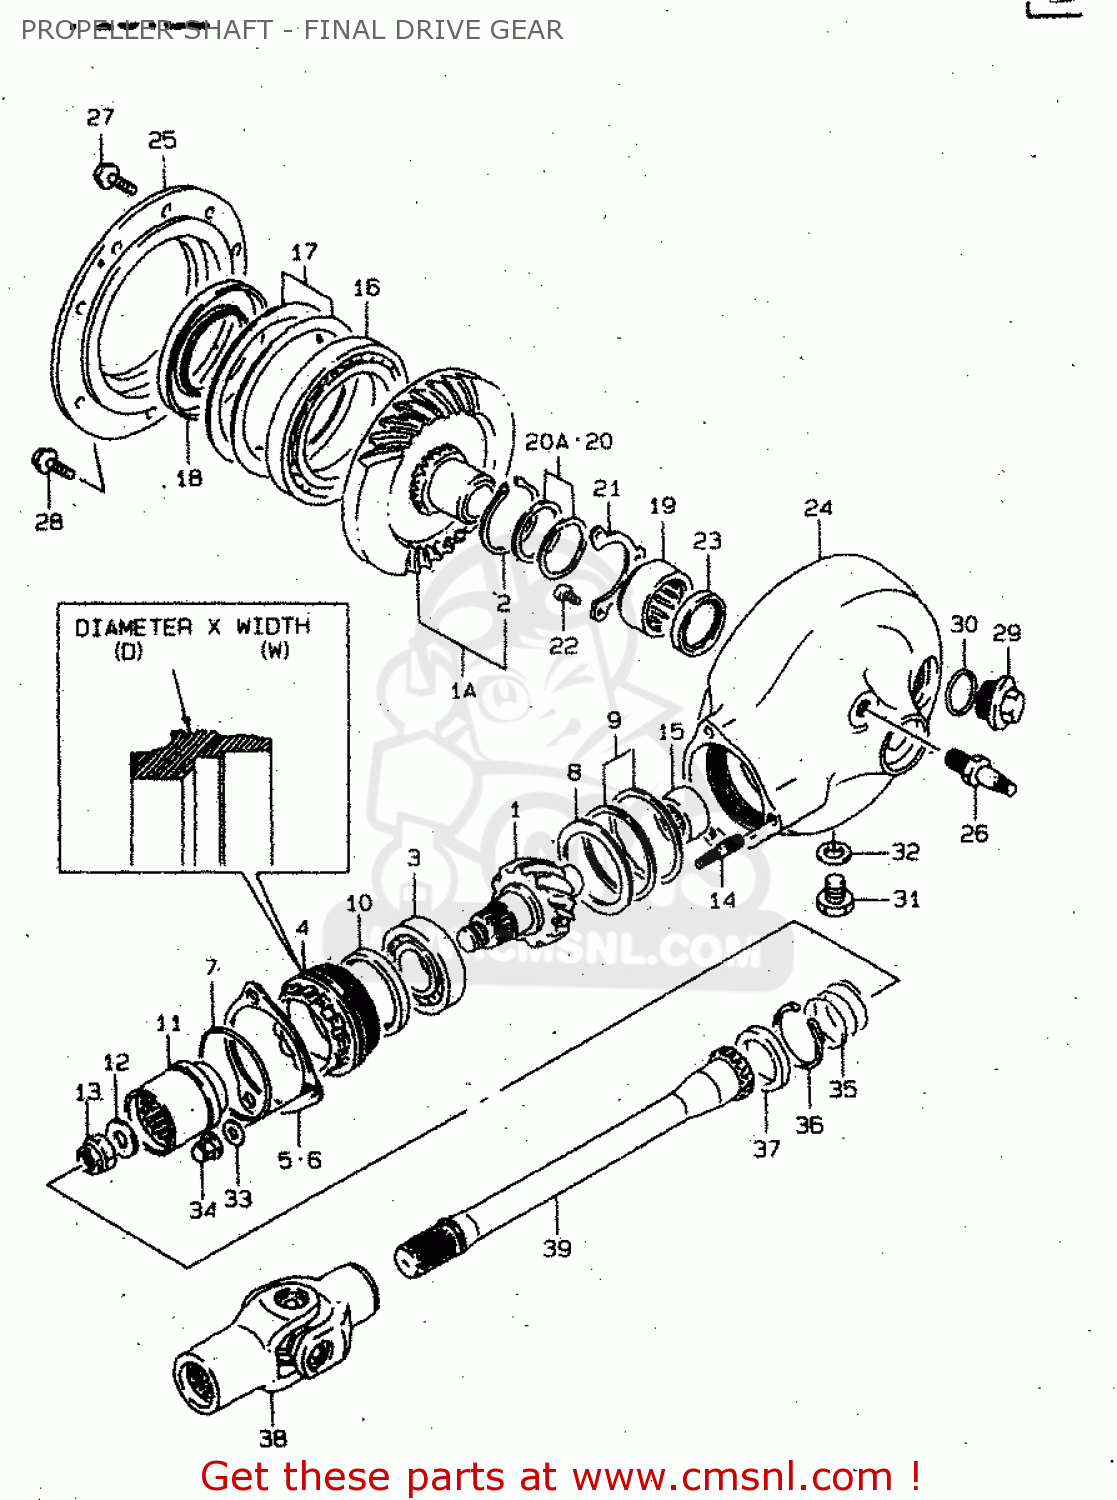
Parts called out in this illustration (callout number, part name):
1	GEAR,FINAL DRIVE BEVEL
1A	GEAR,FINAL DRIVEN BEVEL
2	.CIRCLIP
3	BEARING(28X68X18)
4	STOPPER,FINAL DRIVE BEARING
5	PLATE,BEARING STOPPER
6	PLATE,BEARING STOPPER
7	O RING(D:3.1,ID:63.9)
8	WASHER(54X68X1.5)
9	SHIM SET,FINAL DRIVE GEAR
10	SEAL,OIL
11	COUPLING,FINAL DRIVE GEAR
12	WASHER(16X29X4)
13	NUT
14	STUD 10X25
15	BEARING(20X34X18)
16	BEARING(85X130X14)
17	SHIM SET,FINAL DRIVEN GEAR
18	SEAL,OIL(70X110X14.7)
19	BEARING(35X48X23.7)
20	WASHER(35X46X0.95)
20A	SHIM SET,FINAL DRIVEN GEAR
21	RETAINER,FINAL DRIVEN GEAR BRG
22	SCREW
23	SEAL,OIL(35X43X5)
24	CASE,FINAL GEAR
25	CASE,FINAL GEAR BEARING
26	BOLT,STUD
27	BOLT
28	BOLT
29	PLUG,30X9
30	O RING(D:3.1,ID:26.4)
31	PLUG
32	GASKET(13.8X18.8X4.8) (NAS)
33	WASHER
34	NUT
35	SPRING
36	CIRCLIP
37	SEAL,OIL(30X40.5X5.5)
38	YOKE COMP,UNIVERSAL JOINT
39	SHAFT,PROPELLER
